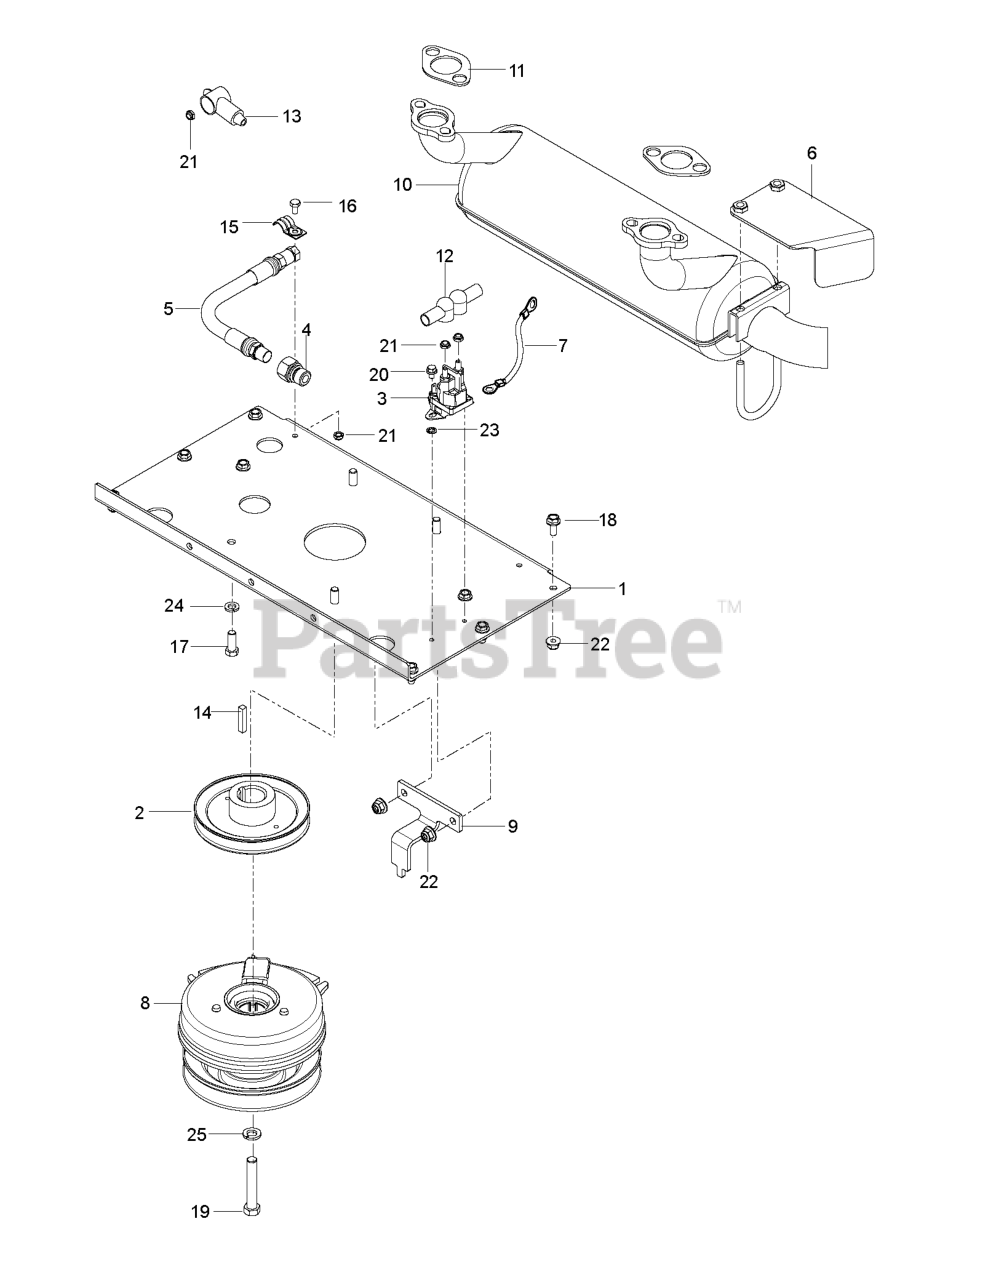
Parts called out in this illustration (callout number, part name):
1	PLATE.PNT.ENGINE.E-DIP
2	PULLEY, V, 1.125 BORE
3	SOLENOID.STARTER.BRASS.PLUNGER
4	ADAPTER, OIL DRAIN
5	HOSE.ASSEMBLY.OIL.DRAIN
6	SHIELD MUFFLER
7	CABLE POSITIVE
8	CLUTCH 200 FT LB
9	STOP, CLUTCH, BLACK
10	MUFFLER.26HP.KAW.FX651V-730V
11	GASKET.EXHAUST.KAWASAKI
13	INSULATOR
14	KEY, 1/4 SQ X 1 1/4
16	HCS 1/4-20.
17	HCS 3/8-16X1.GRD.5.ZD
18	HHFS 5/16-18 X 3/4
19	CLUTCH BOLT7/16-20X2.5 GR596HR
20	HWST 1/4C X 3/8
21	JAM NUT 1/4C (2 2 PW01)
22	5/16-18 NYLOC FLANGE NUT
23	WASHER 1/4 INT TOOTH
24	SLW 3/8 STD
25	WASHER 7/16 LOCK
